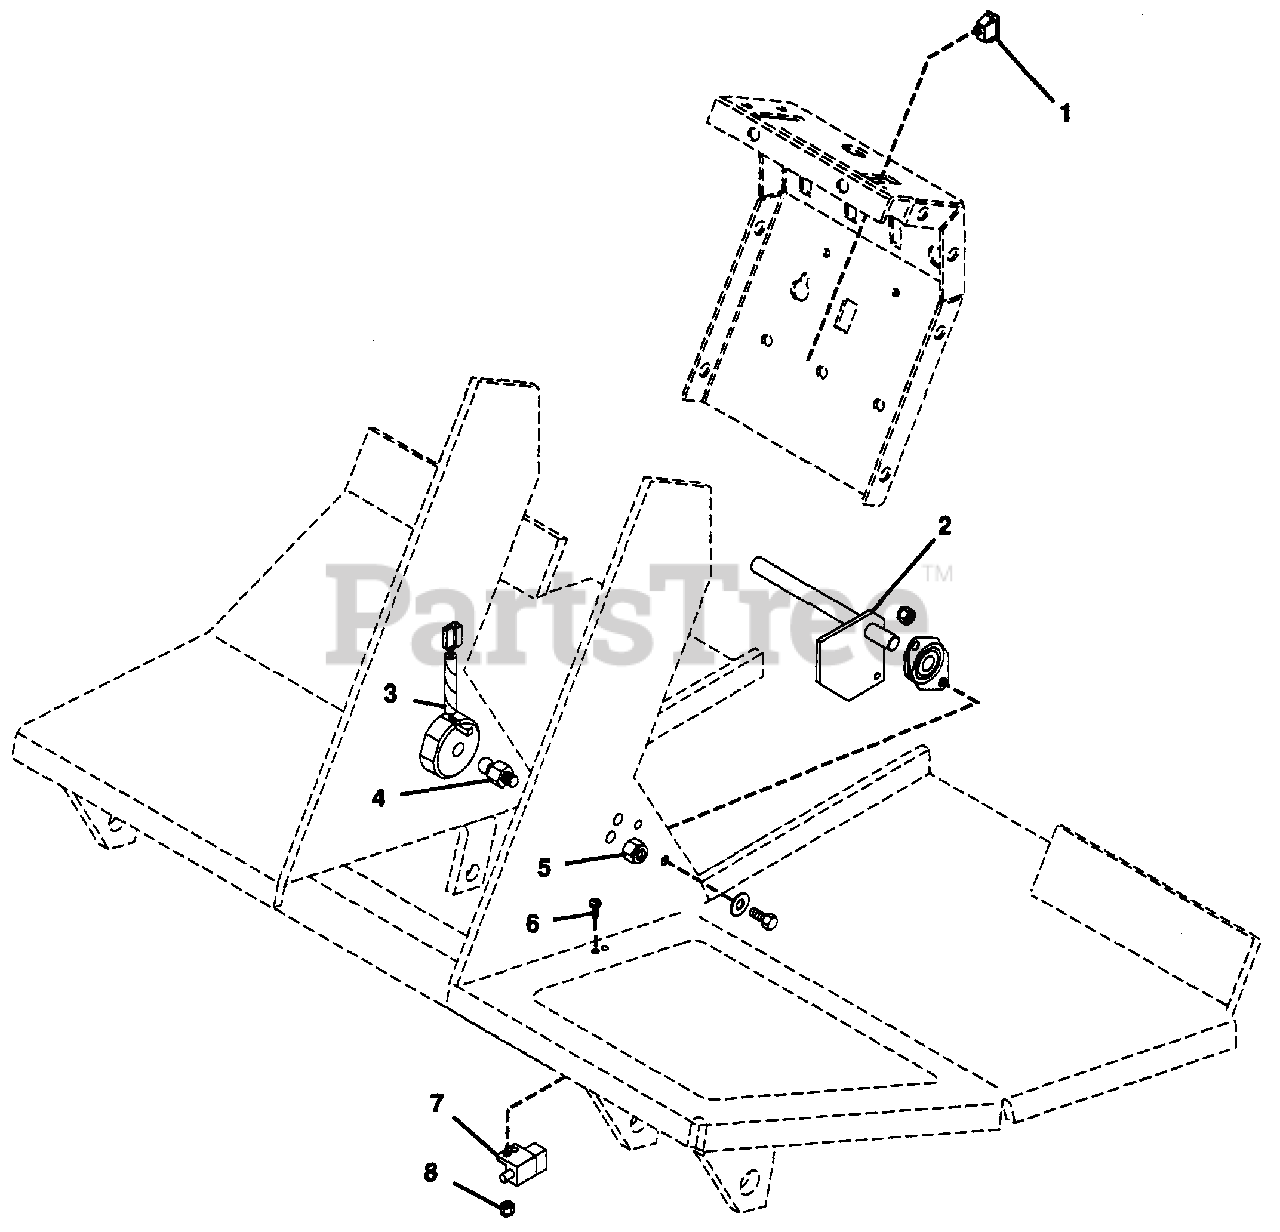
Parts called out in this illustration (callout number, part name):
1	Switch, Light
2	Weldment, Control
3	Assembly, Magnet
4	Pin, Magnet
5	Nut, Lock 1/2-13
6	Screw, Machine 10-24x.625 PHD
7	Switch, Interlock
8	Nut, Lock 10-24
